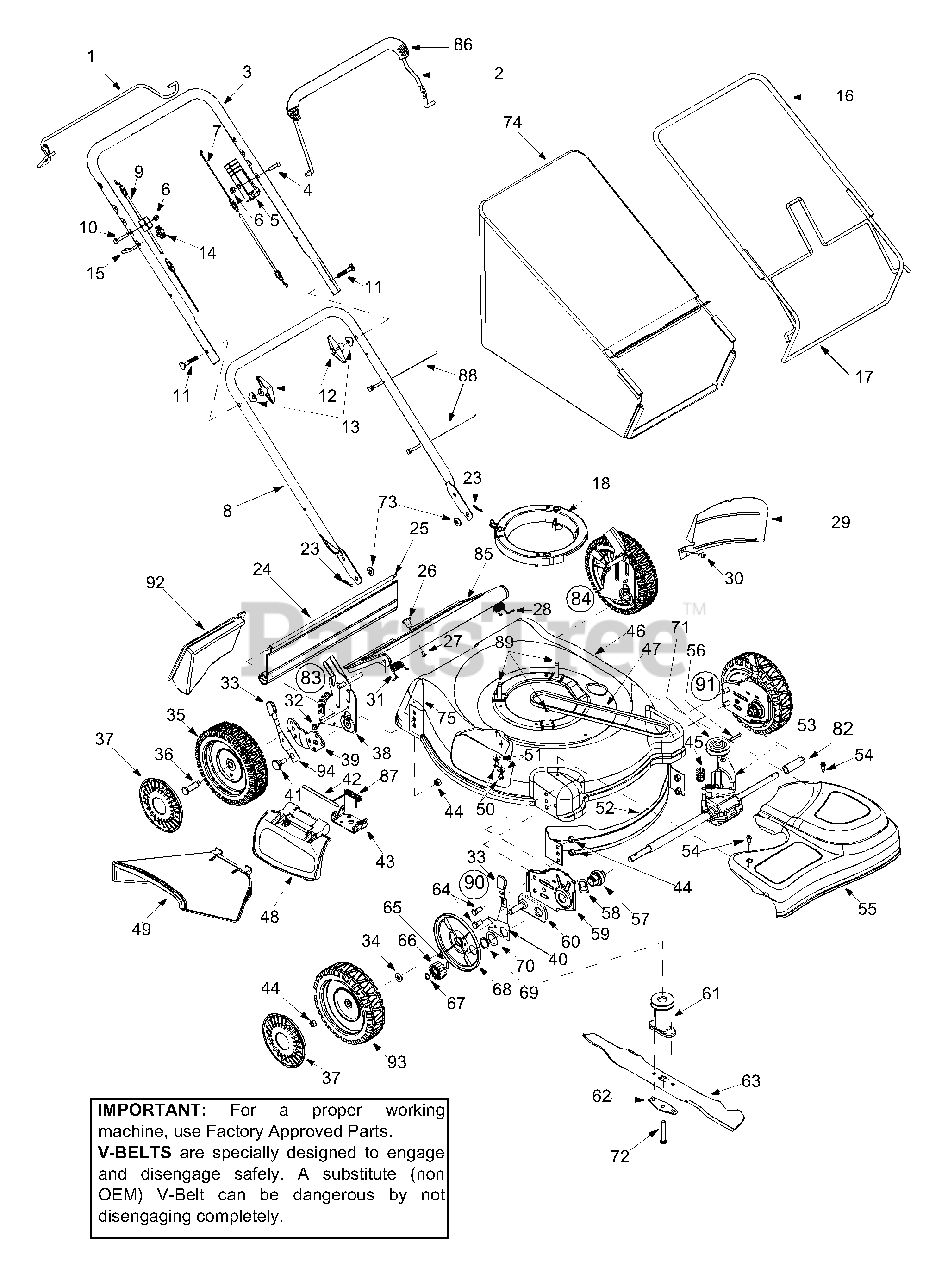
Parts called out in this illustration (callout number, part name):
5	Control Housing
6	Hex Lock Nut 1/4-20
7	Control Cable: 43"
9	Drive Cable
10	Hex Screw 1/4-20 x 1.5"
11	Carriage Bolt
12	Handle Knob
13	Saddle Washer
14	Wing Nut
15	Rope Guide
23	Hairpin Clip
24	Rear Trail Shield
25	Wire: Trail Shield
27	Scr. Tr. Mach. #10-24 x 0.380"
28	Torsion Spring LH
30	Scr. AB 1/4-14 x 0.625"
31	Torsion Spring RH
32	Hex Scr. w/ Wash. 1/4-14 x 0.62"
33	Knob
34	Bell Washer.375 x.870
35	Wheel: Rear
36	Shoulder Screw
37	Hubcap
39	Pivot Bar RH
40	Front Lever RH
41	Shoulder Screw
42	Hinge Pin
44	Flange Lock Nut
45	Belt Tension Spring
48	Hinged Mulch Plug
49	Discharge Deflector SD
50	TT Screw 1/4-20 x 0.5"
51	Bell Washer 0.265" x 0.75"
54	Shoulder Screw
55	Front Drive Cover: Black
56	Roll Pin
57	Bearing Assembly
58	Wave Washer
61	Blade Adapter w/ Pulley
62	Blade Bell Support
63	Mulching Blade w/ Star: 21"
64	Hex Screw
65	Dowel Pin
66	Gear 14T RH
67	Snap Ring
68	Wheel Dust Cap
69	Snap Ring
70	Washer DD 1.5" O.D.
71	Input Pulley
72	Hex Bolt
73	Flat Washer
74	Grass Bag
82	Slev. Spacer RH
83	Height Adj. Assembly RH Compl.
84	Height Adj. Assembly LH Compl.
87	Torsion Spring
88	Cable Tie
89	TT Screw
90	Height Adj. Assembly RH Compl.
91	Height Adj. Assembly LH Compl.
92	Rear Mulching Baffle
93	Wheel: Front
94	Spring Lever
